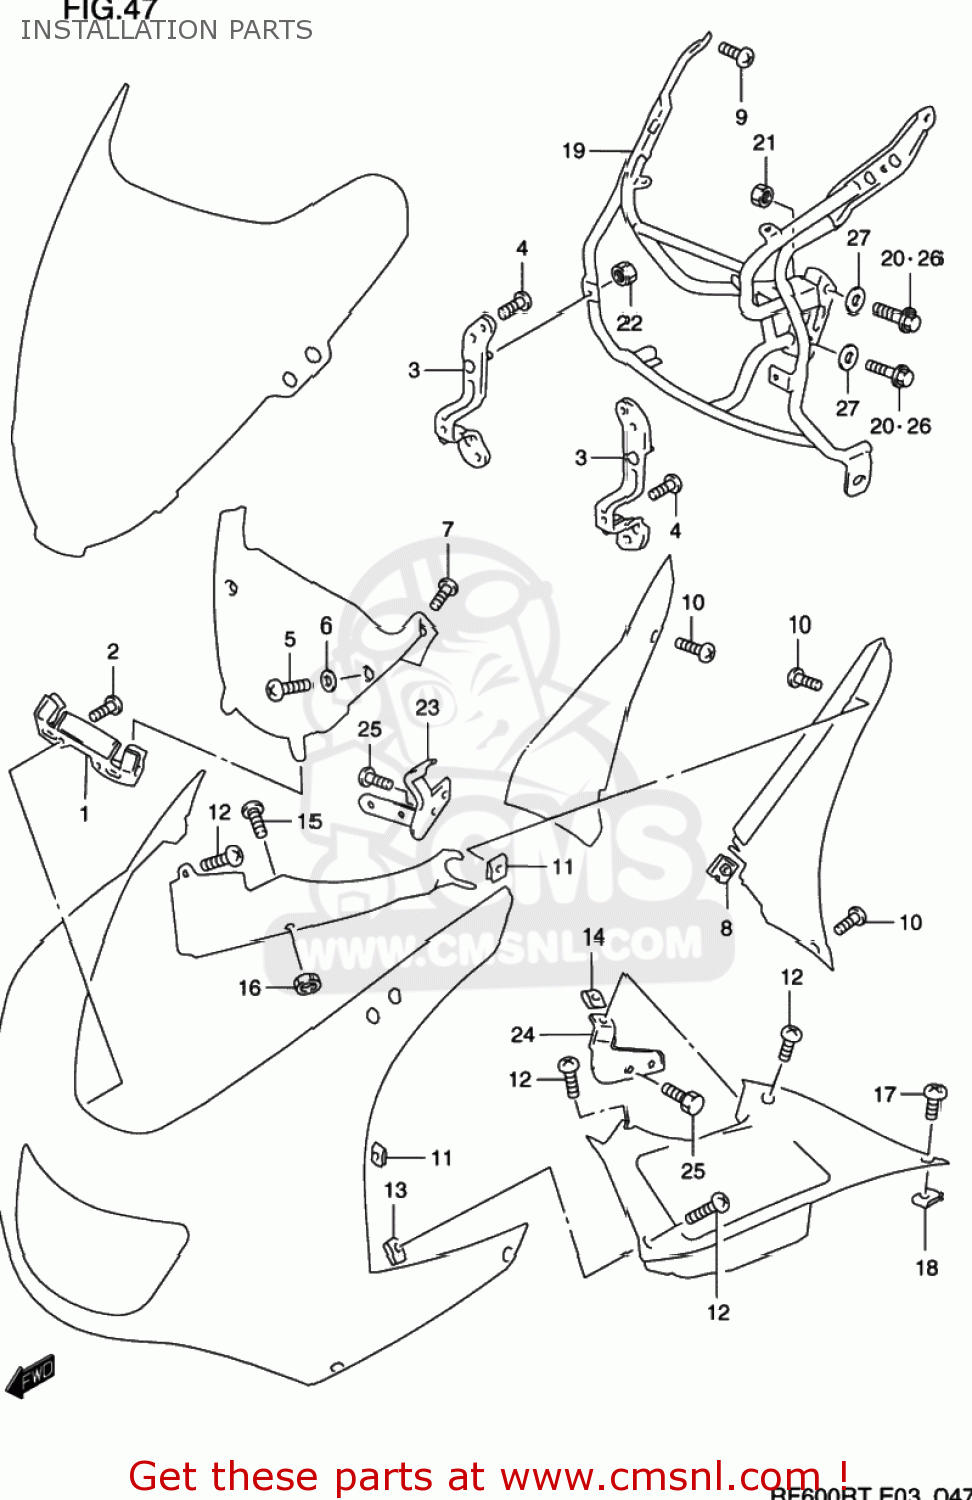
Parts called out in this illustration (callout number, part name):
1	SCREW
2	NUT
3	SCREW 5X10
4	SCREW
5	WASHER(5.2X14X1.5)
6	NUT,HEADLAMP HOUSING,UPPER
7	SCREW 5X10
8	SCREW
9	WASHER(5.2X14X1.5)
10	NUT,HEADLAMP HOUSING,UPPER
11	SCREW
12	WASHER(5.2X14X1.5)
13	NUT,HEADLAMP HOUSING,UPPER
14	CUSHION
15	SCREW
16	WASHER(5.2X14X1.5)
17	NUT,HEADLAMP HOUSING,UPPER
18	BOLT
19	SPACER (6.1X9X10)
20	CUSHION
21	BOLT
22	SPACER (6.1X9X10)
23	CUSHION
24	BRACKET,UNDER COWLING LWR,R
25	BOLT
26	SPACER(6.1X10X16)
27	SCREW 5X12
28	WASHER(5.2X14X1.5)
29	BRACKET,RR UNDER COWLING FTG
30	NUT
31	SCREW
32	WASHER(5.2X14X1.5)
33	NUT,HEADLAMP HOUSING,UPPER
34	BRACKET,UNDER COWLING UPR,R
35	CUSHION,UNDER PANEL
